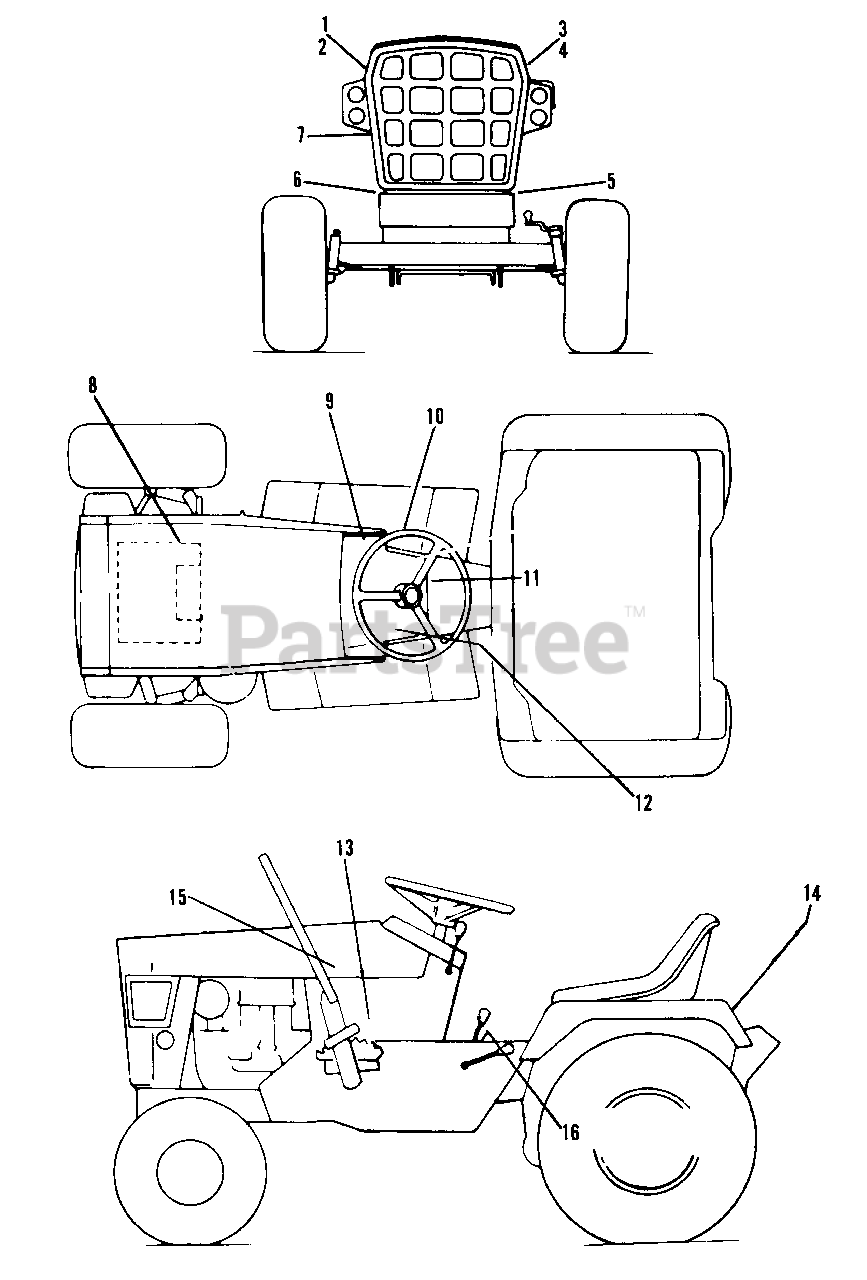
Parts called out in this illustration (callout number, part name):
1	DECAL, Hood, L.H.
2	DECAL, L.H.
3	DECAL, Hood, R.H.
4	DECAL, R.H.
5	DECAL, Brake
6	DECAL, Clutch
7	DECAL, Safety
8	DECAL, Oil Level Inst.
9	DECAL, Instrument Panel
10	DECAL, Forward & Reverse
11	DECAL, Ignition
12	DECAL, Throttle
13	DECAL, Lift Lever
14	DECAL, Rear Seat Deck
15	DECAL, Battery
16	DECAL, Shift Pattern
